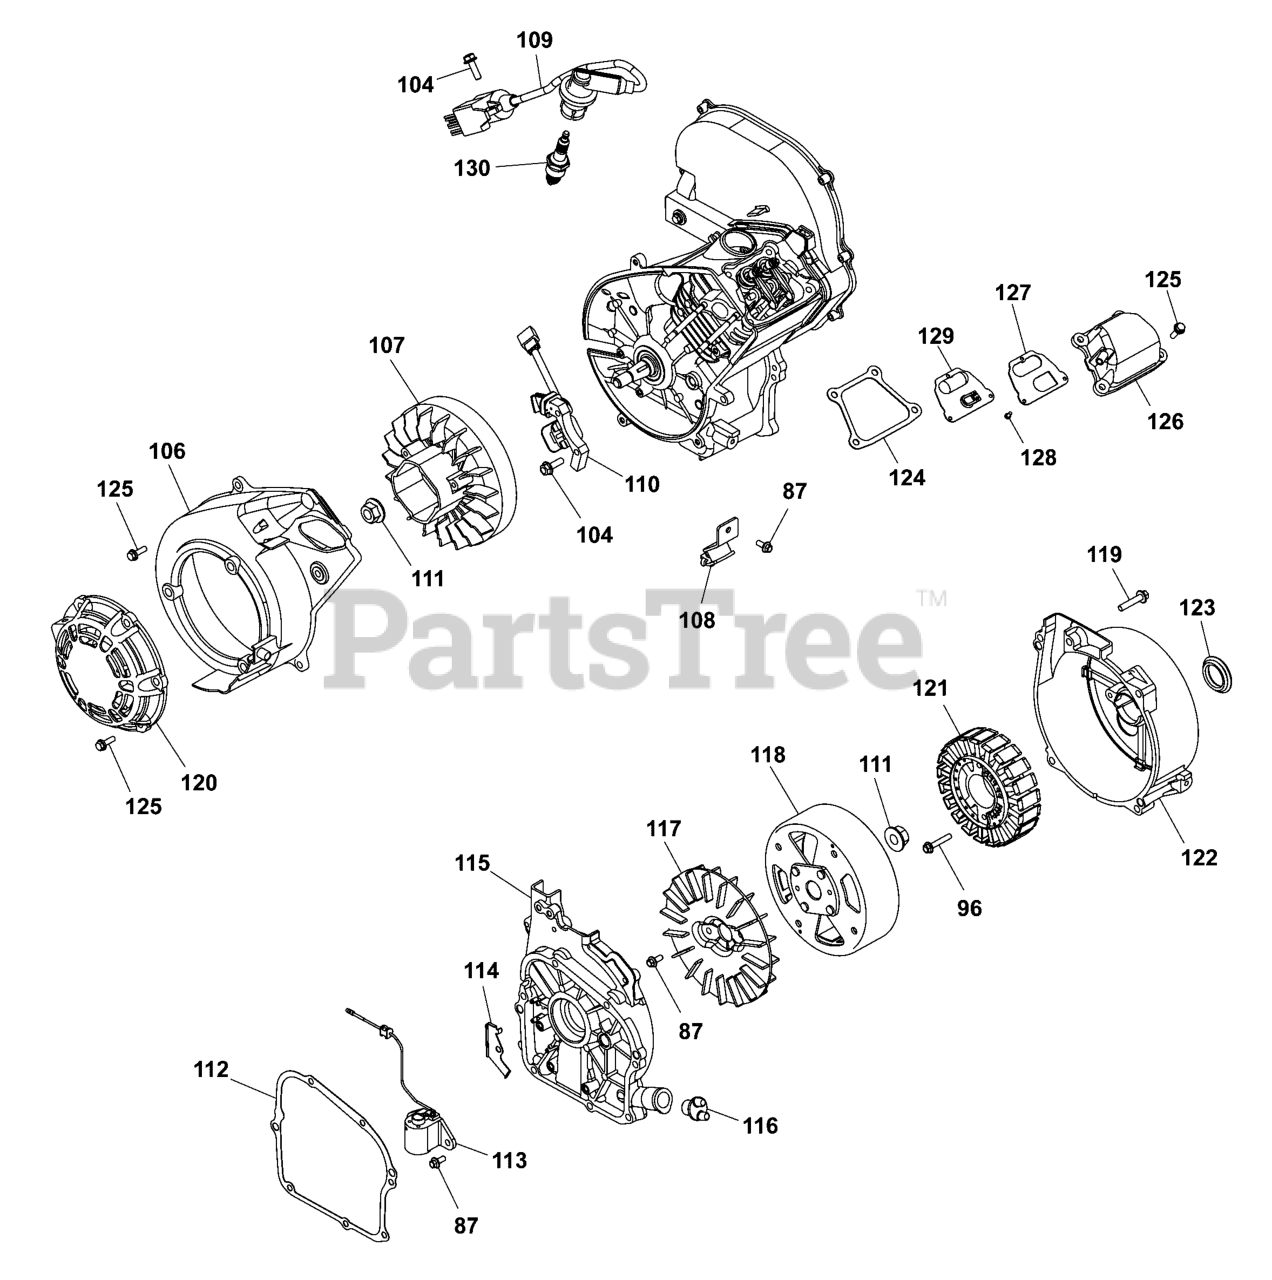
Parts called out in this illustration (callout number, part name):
108	MOUNT-VIBRATION
114	CLAMP
115	COVER, Crankcase
